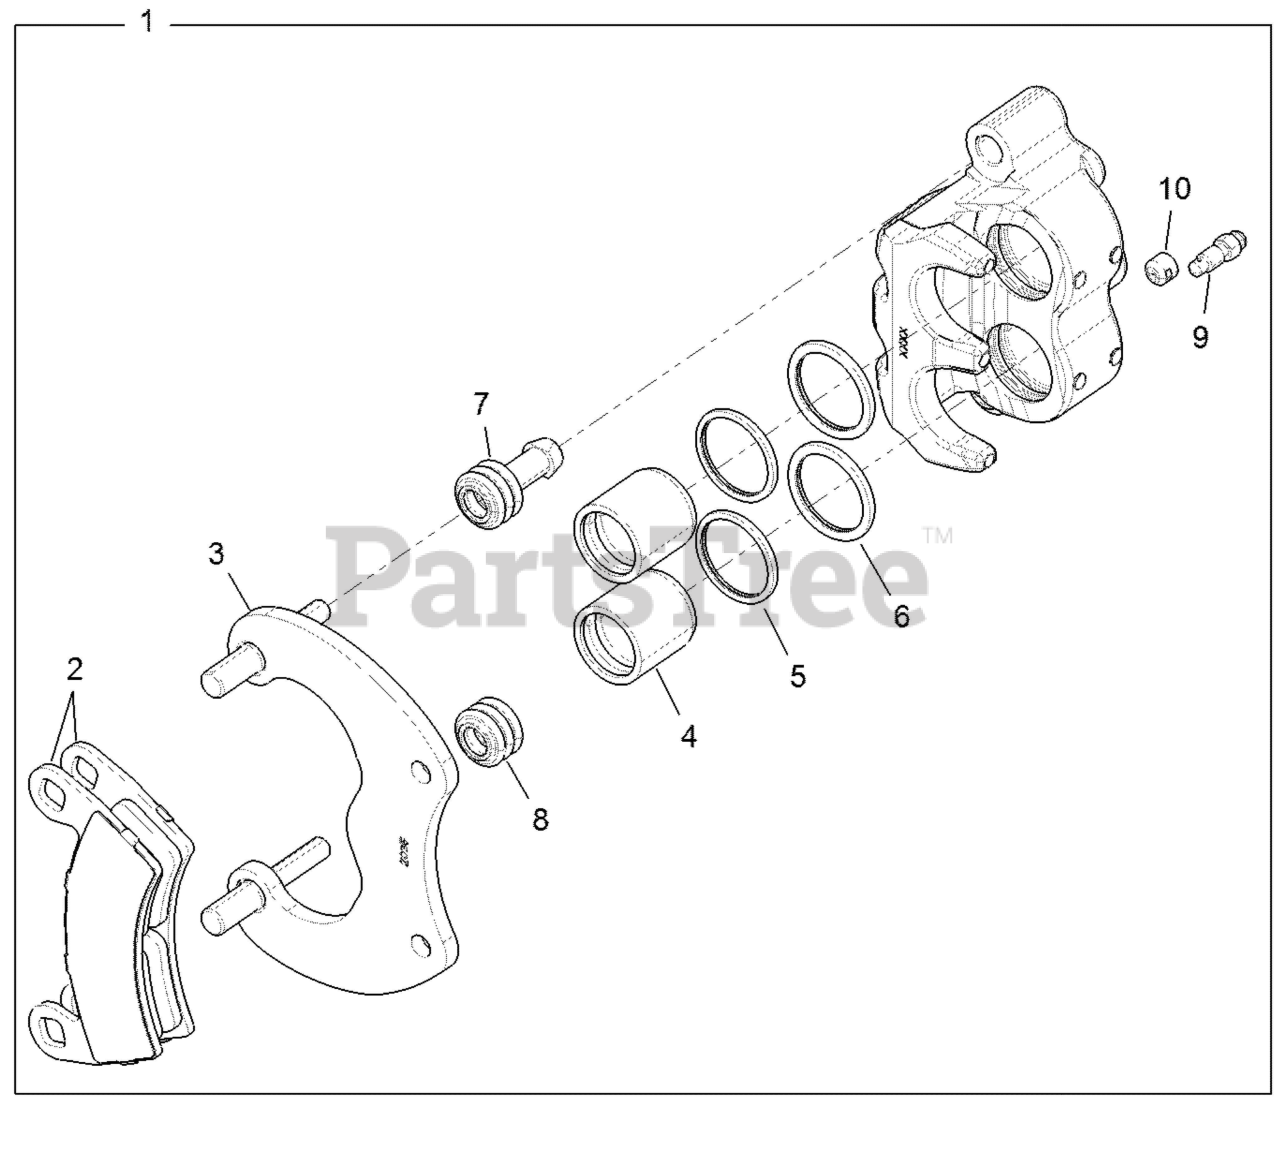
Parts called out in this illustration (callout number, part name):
1	ASM.,BRAKE,CALIPER,LH,GROOVED
1	ASM.,BRAKE,CALIPER,RH,GROOVED
2	KIT-ASM,PAD,BRAKE,DB,1.375
3	ASM., CALIPER, MOUNT
4	PISTON-BRAKE,1.188",AL,GROOVED
5	RING,SQUARE,MOLDED,.094
6	RING,SQUARE,MOLDED,.103X.134
7	BOOT-PIN BUSHING
8	BOOT-PIN SEAL
9	SCR-M7X1.0,BLEEDER,OLIVE D
10	SCR-M10X1.0X8,SOC SET-OD
